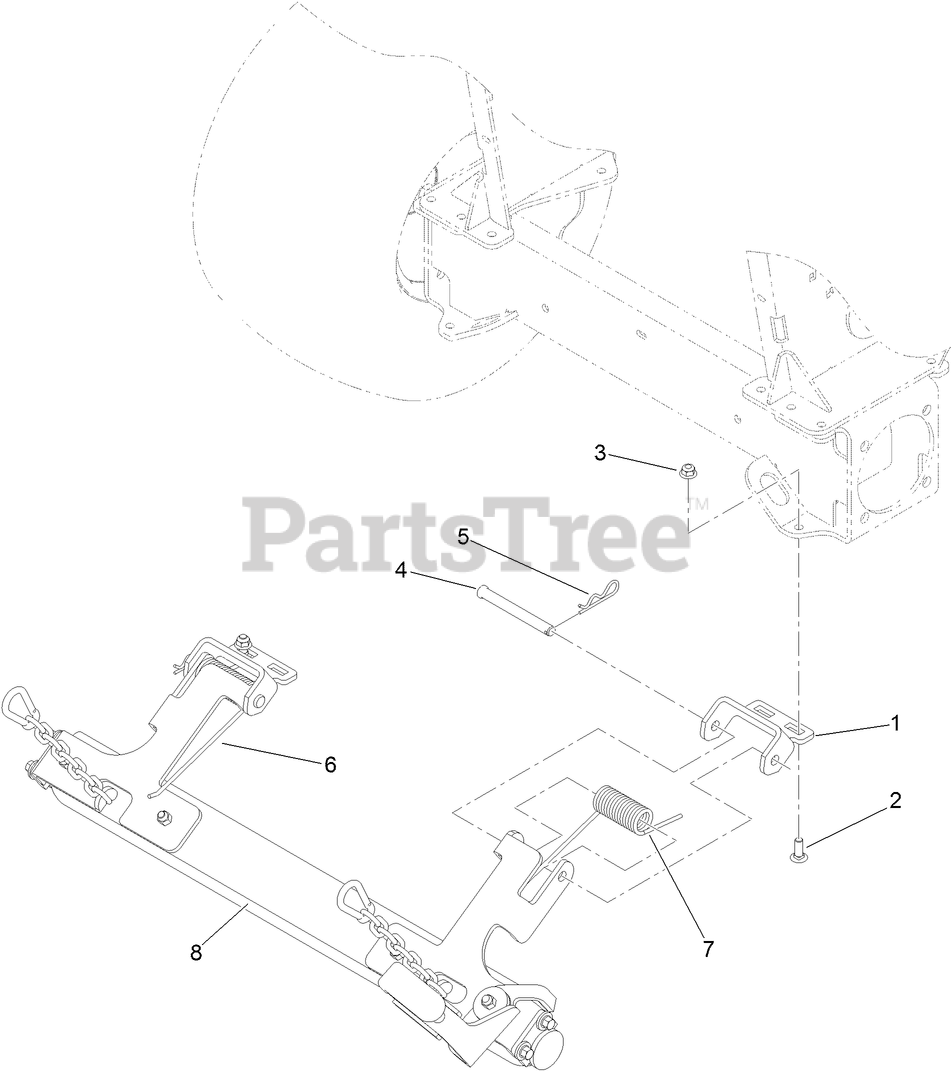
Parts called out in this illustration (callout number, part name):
1	BRACKET-MOUNT, STRIPER
2	SCREW-CARR
3	NUT-HF, NI
4	PIN-CLEVIS
5	PIN-HAIR
6	SPRING-TORSION
7	SPRING-TORSION
8	ROLLER ASM
